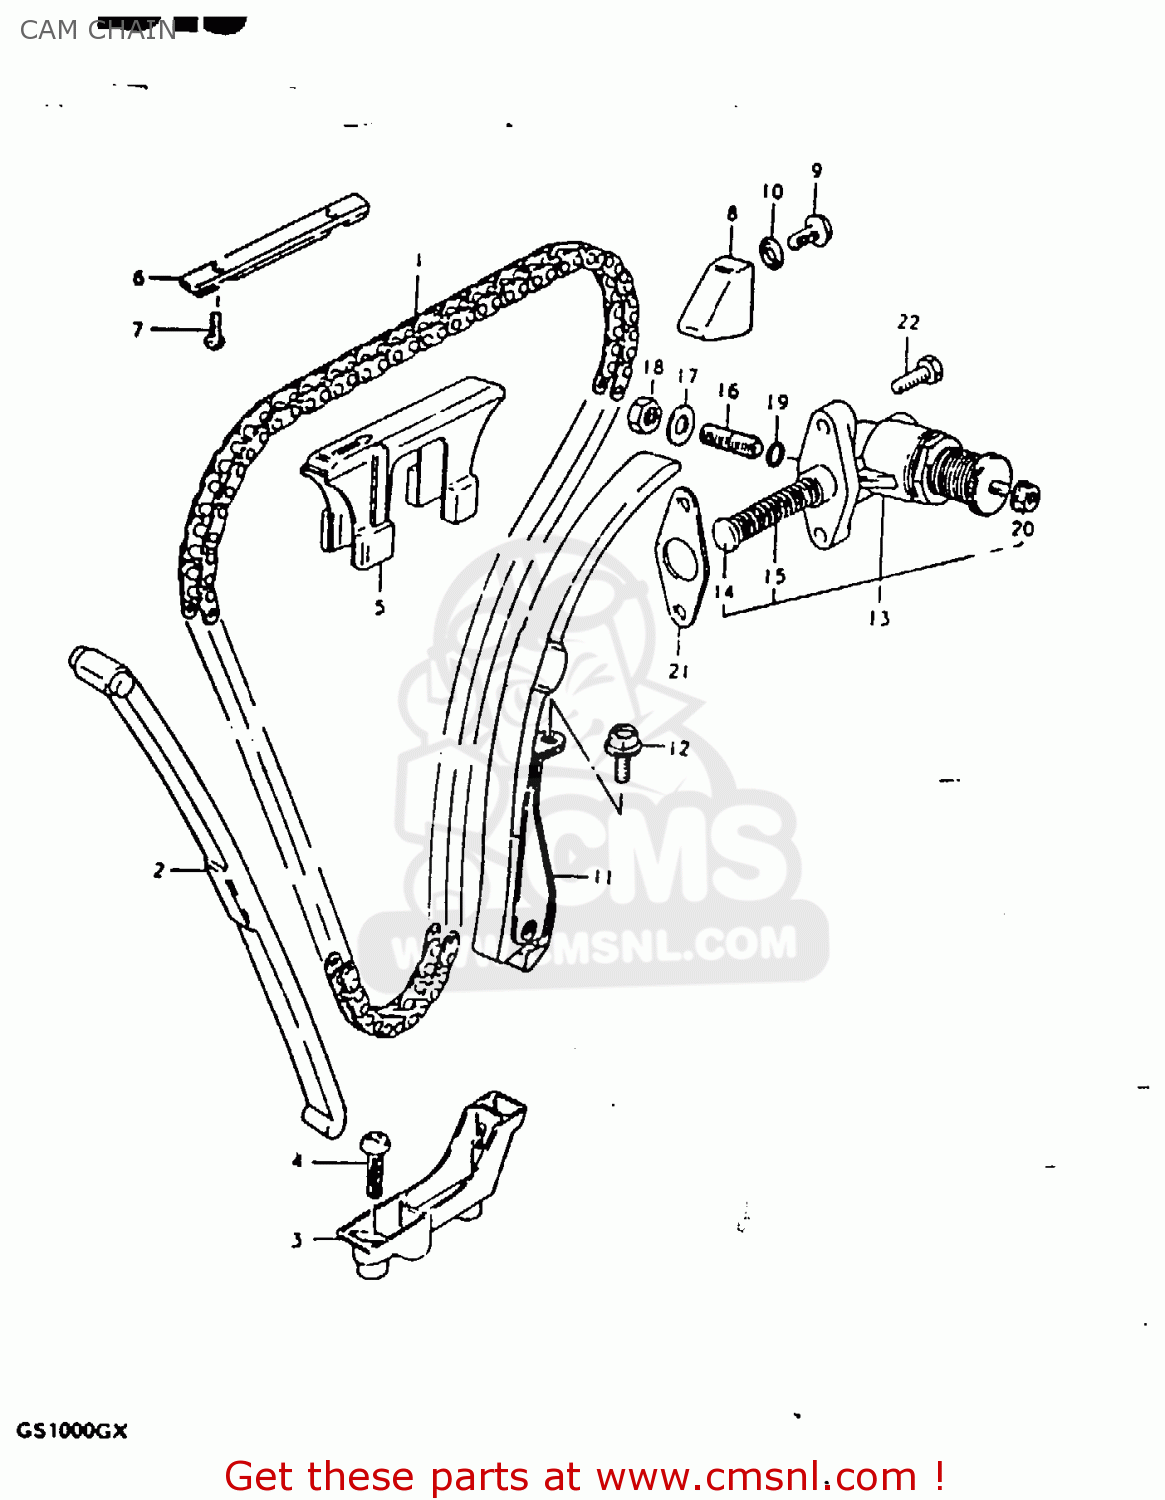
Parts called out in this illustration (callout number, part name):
1	CHAIN,CAMSHAFT DRIVE
2	GUIDE,CAM CHAIN NO.1
3	HOLDER,CAM CHAIN GUIDE
4	SCREW
5	GUIDE,CAM CHAIN NO.2
6	GUIDE,CAM CHAIN
7	SCREW
8	GUIDE,CAM CHAIN
9	BOLT
10	GASKET (NAS)
11	TENSIONER,CAM CHAIN
12	BOLT
13	ADJUSTER ASSEMBLY,TENSIONER
14	ROD,PUSH
15	SPRING
16	SCREW
17	WASHER
18	NUT
19	O-RING
20	NUT
21	GASKET,TENSIONER ADJUSTER (MCA)
22	SCREW (6X25)
